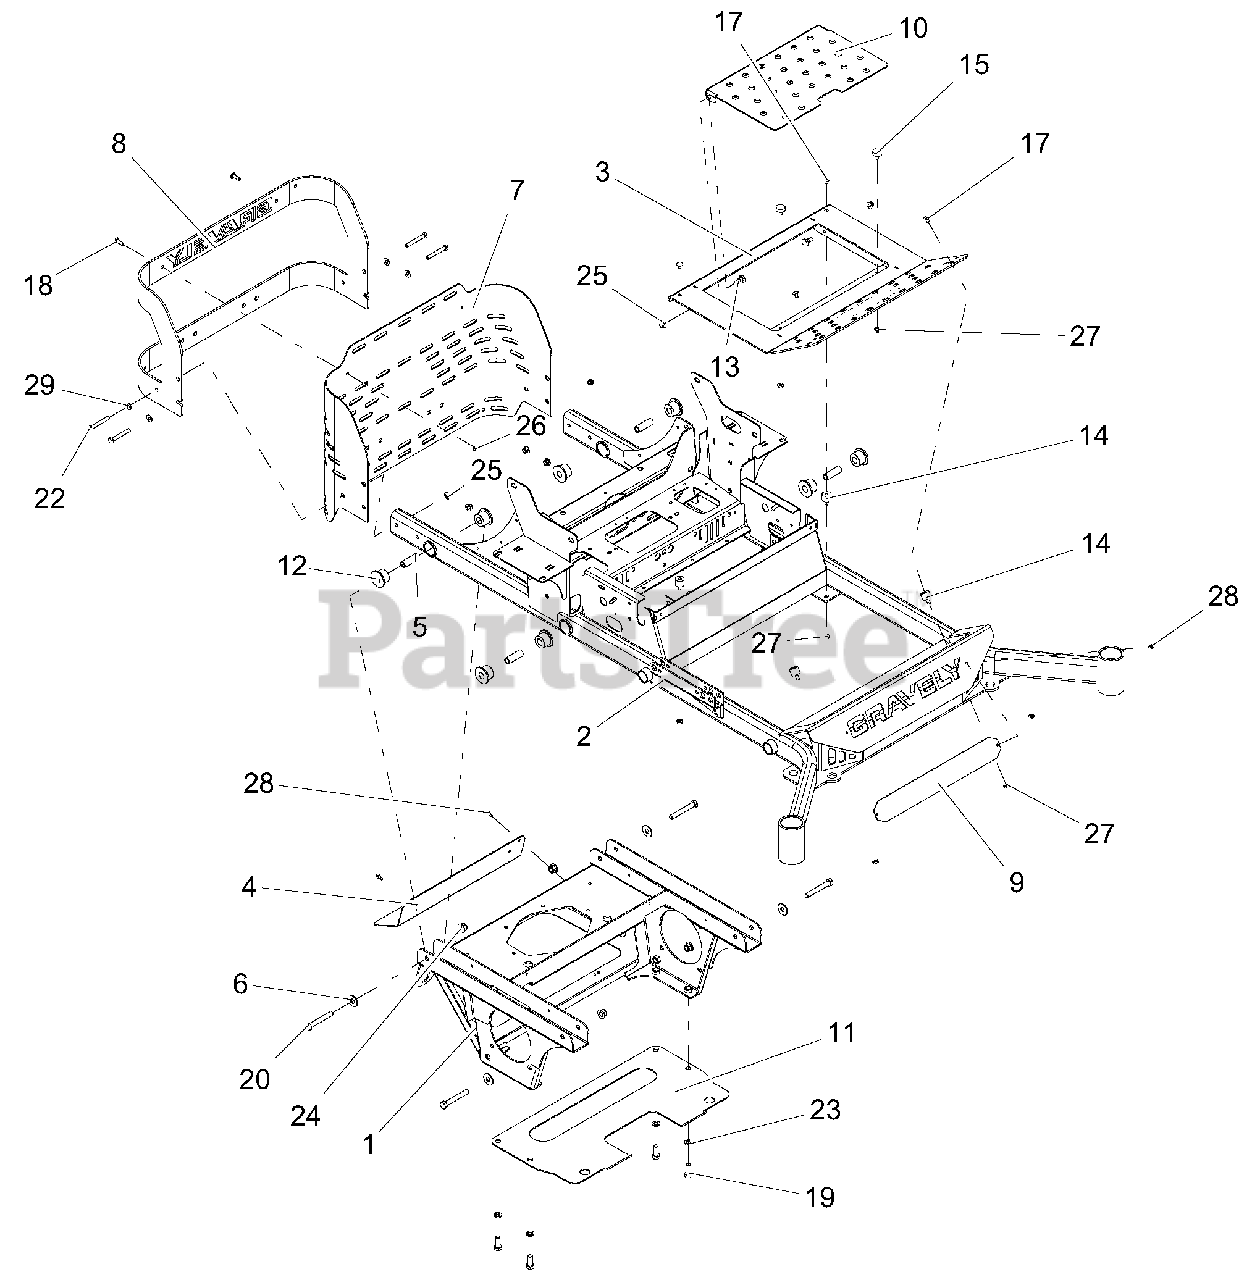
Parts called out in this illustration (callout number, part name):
1	WLDT, 200 PT AXLE/ENGINE FRAME
2	72" PT200/400 MAIN FRAME WITH SAFTEY DECALS
3	FOOTPLATE WLDMT W/SAFETY DECAL
4	SHIELD, MUFFLER HEAT-BLACK
5	SPCR, .50 X .75 X 2.23 YZ
6	WSHR-FL-STL.563X1.38X.109YWZC
7	GUARD, REAR BUMPER FINGER-BLACK
8	REAR BUMPER W/SAFETY DECALS-GAS
9	PLATE, BUMPER LOGO BACKING-BLACK
10	INSPECTION PANEL W/SAFETY DECAL
11	PLATE-TRANSMISSION SKID-RED
12	BSHG, FLG .75 X 1.51 X 2.00 X .18
13	BLT, SHLDR EP .38-16X.30 HEX YZ
14	BUMPER, STUD MOUNTED W/FEMALE INSERT
15	BUMPER, RUBBER
17	BLT-RDHDSQNK .31-18X.50 G5 YWZC
18	BLT-RDHDSQSHNK .31-18X1.00 G5YWZC
19	BLT-HEX .50-13X1.25 GR5 YWZC
20	BLT-HEX .50-13X3.50 GR5 YWZC
22	BLT-HEX .38-16X2.75 GR5 YWZC
23	WSHR-LK .50X.125 REG YWZC
24	NUT-LK-NYL-FLG .50-13 YWZC
25	NUT-LK-NYL-FLG .38-16 YWZC
26	NUT-LK-NYL-FLG .31-18 YWZC
27	@NUT-SPNLK-FLG .312-18 YWZC
28	SCR-TAP .25-20X.50 HWH TR YWZ
29	WSHR-FL-STL.406X.812X.065 YWZ
